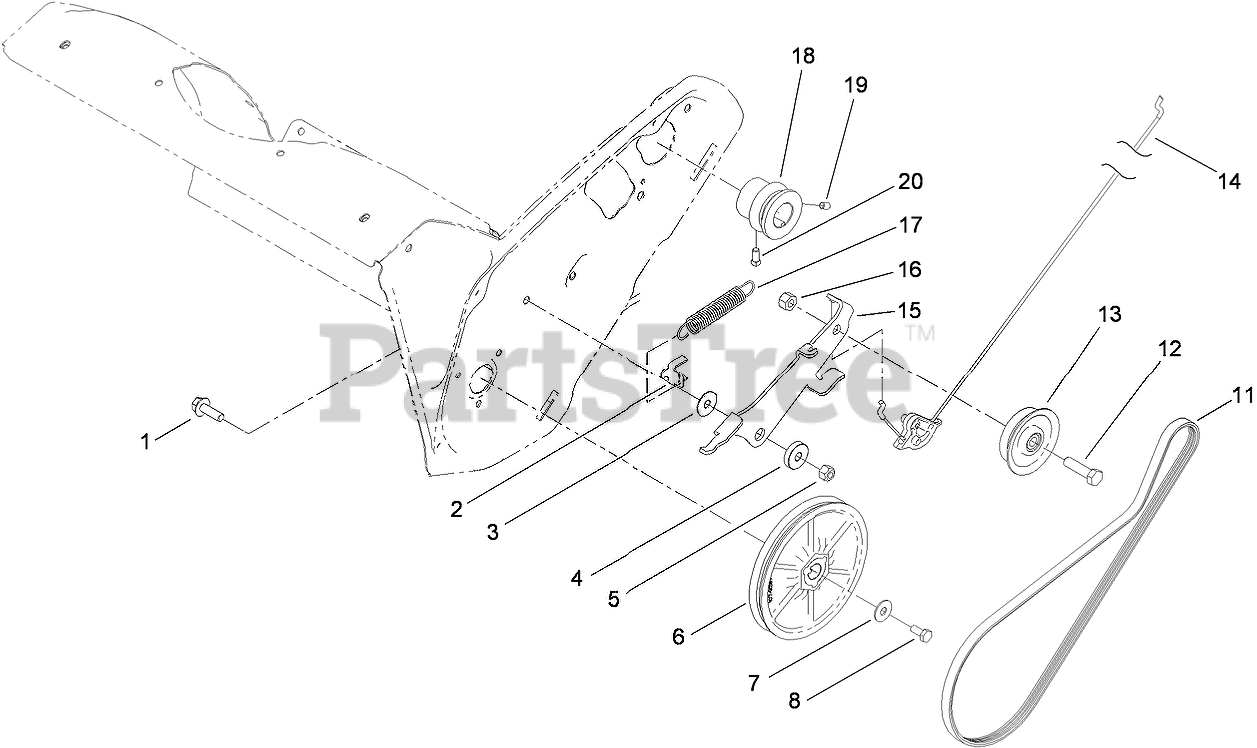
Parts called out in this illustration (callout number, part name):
1	SCREW-HHF
2	CLIP-SPRING, BRAKE
3	WASHER
4	BUSHING-PIVOT
5	NUT-LOCK, NI
6	ROTOR PULLEY ASM
7	WASHER-BELLEVILLE
8	SCREW-HH
11	BELT-DRIVE
12	SCREW-HH
13	PULLEY-IDLER
14	CABLE-CLUTCH
15	ARM-IDLER
16	NUT-LOCK, CONE
17	SPRING-EXTENSION
18	PULLEY-3 GROOVE
19	SCREW-HSH
20	SCREW-SQH
